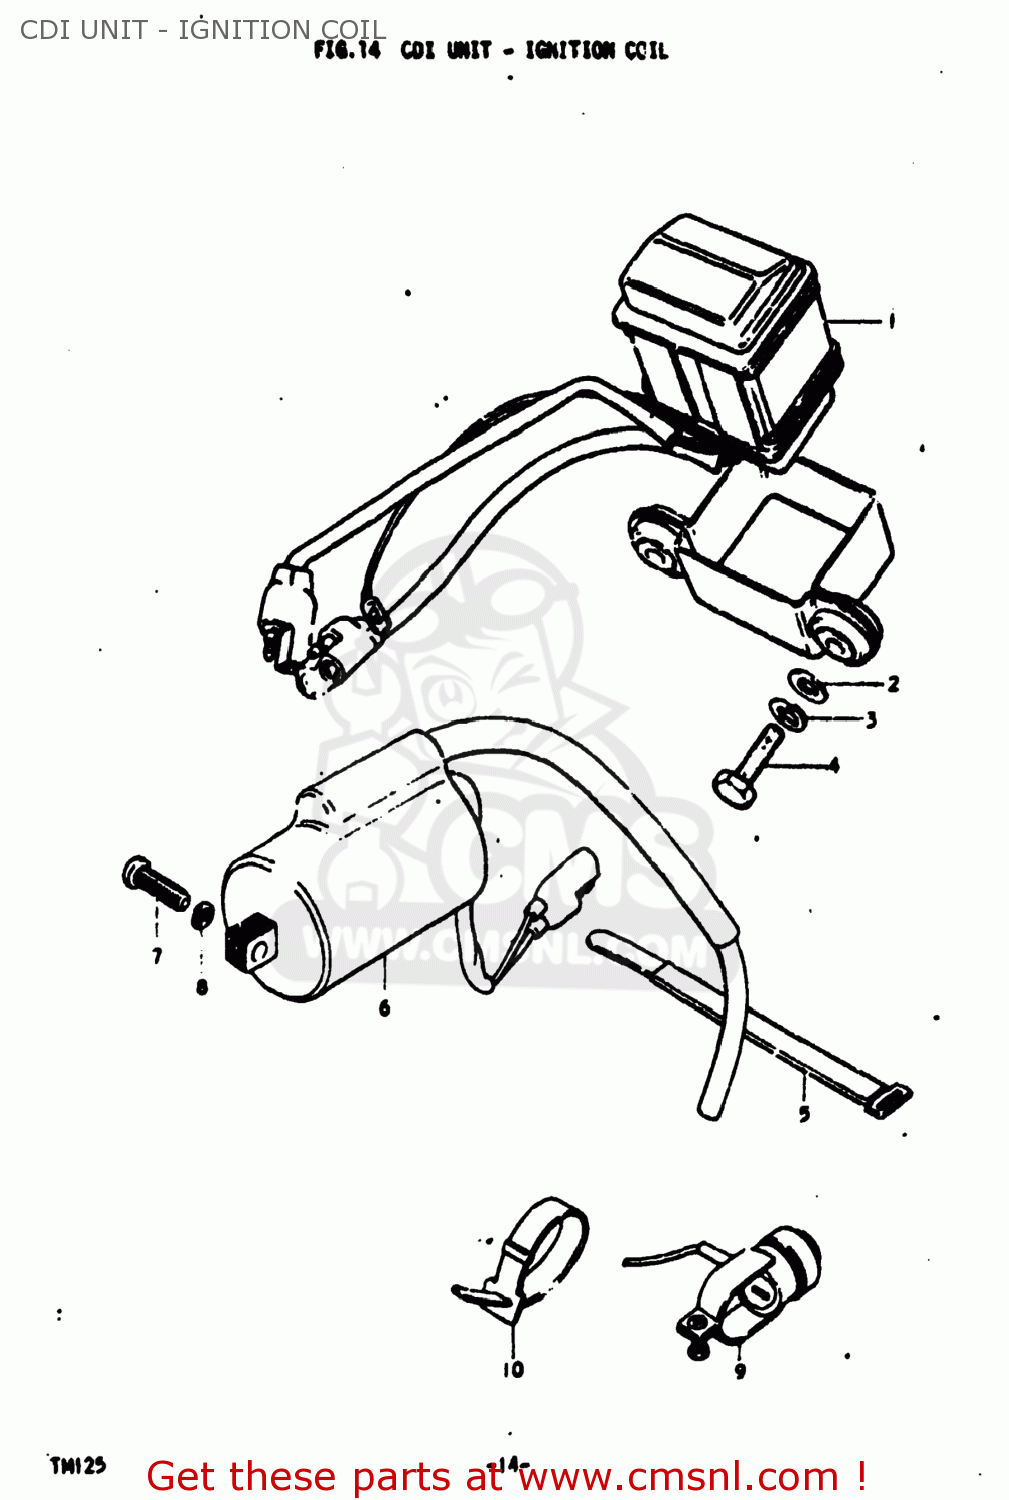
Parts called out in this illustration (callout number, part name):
1	CDI UNIT ASSY
2	WASHER 6MM
3	LOCK WASHER
4	BOLT
5	CLAMP
6	COIL ASSY,IGNITION
7	SCREW
8	LOCK WASHER
9	SWITCH ASSEMBLY
10	CLAMP
